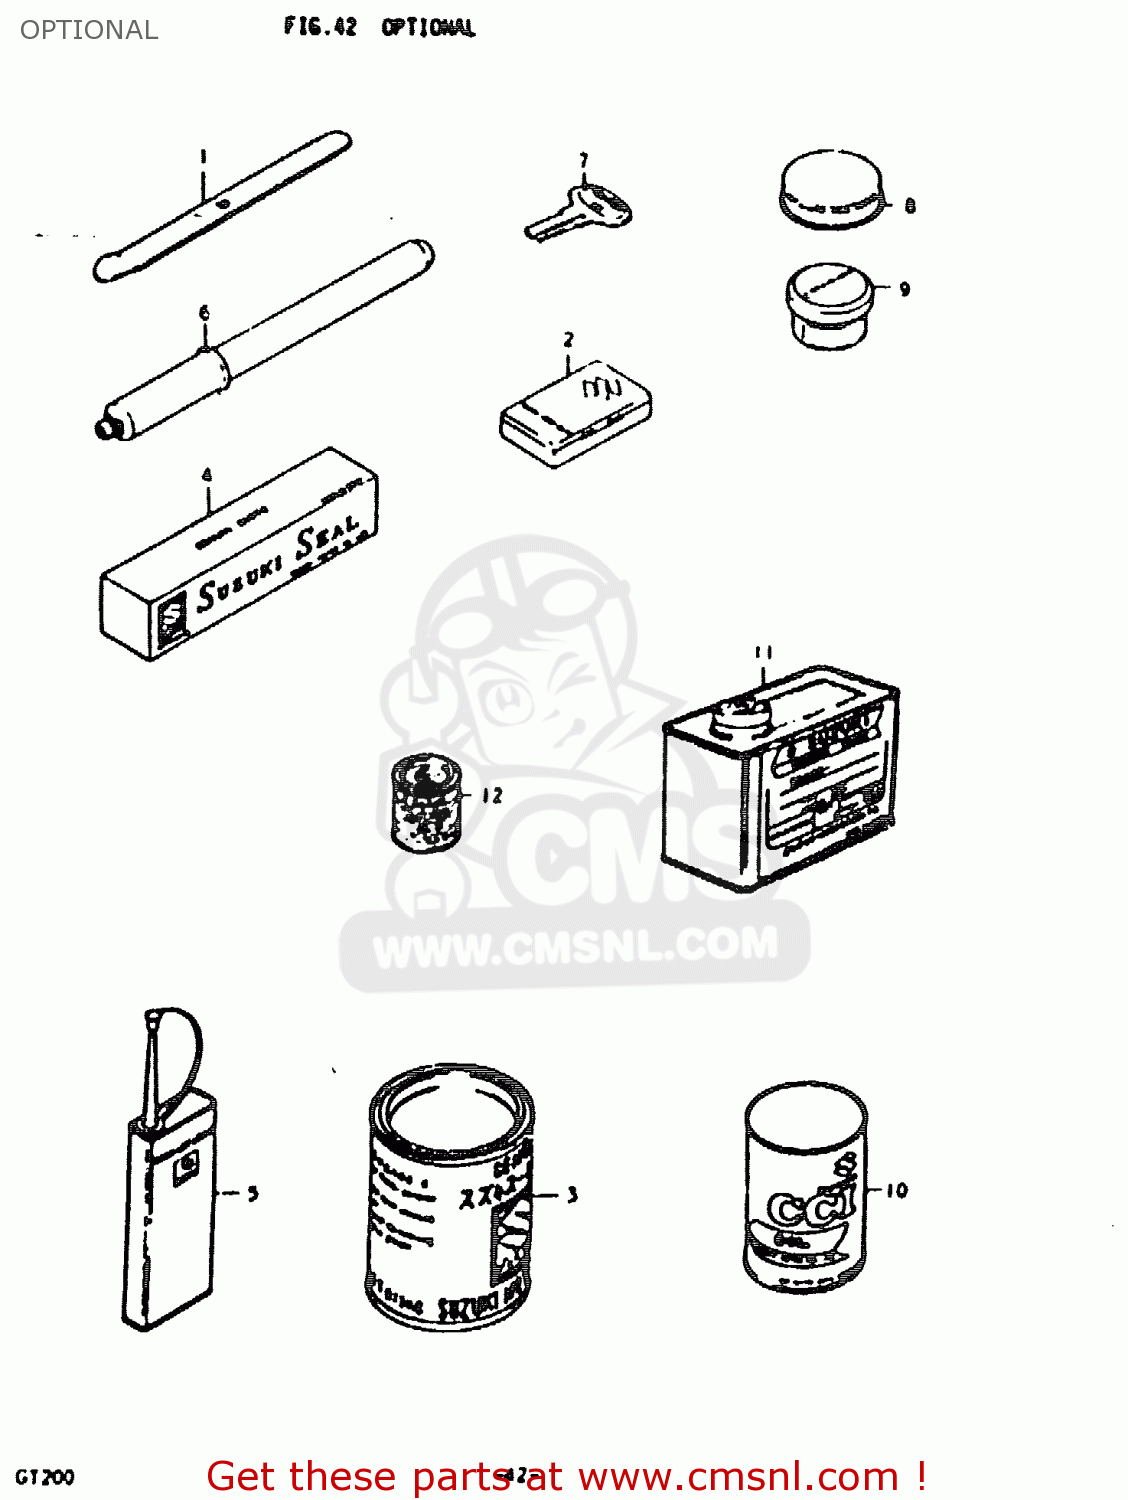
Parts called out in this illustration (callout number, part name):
1	LEVER,TIRE
2	TUBE REPARING TOOL
3	GREASE(C)EP2 LITHIUM 150G
4	LIQUID GSKT 150G BLACK
5	THREAD LOCK NO.1401 CLEAR 200G
6	INFLATOR, AIR
7	KEY,BLANK
10	CCI OIL
11	PAINT (BLACK)
12	PAINT,BLACK
13	GASKET SET
